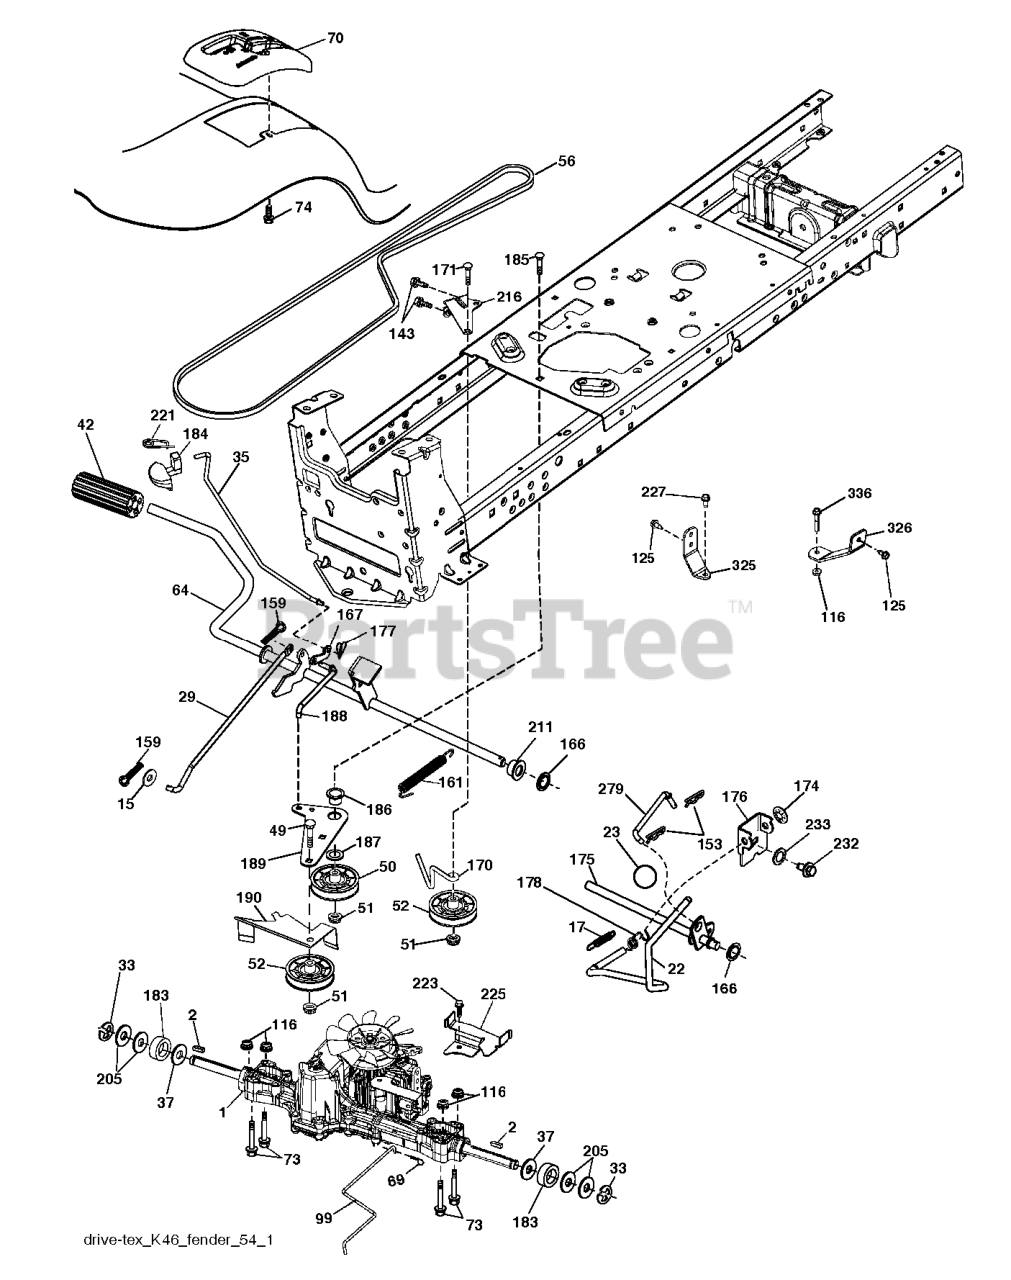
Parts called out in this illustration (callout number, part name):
2	SQUARE KEY
15	WASHER PLAIN WASHER 3/8 X 0.08
17	SPRING.BRAKE.K46.GREEN
22	ROD.SHIFT.FENDER.TLT.2006
23	KNOB.DELUXE.(PISTOL.GRIP).BLAC
29	ROD.BRAKE.K46
35	ROD ROD.PARKINGBRAKE.GT.HUSQ/P
37	WASHER.HARDENED
42	PEDAL COVER
50	IDLER.FLAT.910.OFFSET
51	NUT LOCK FLG 3/8-16 UNC
52	IDLER.V-GROOVE.910.OFFSET
64	SHAFT.ASM.PEDAL.BRAKE.
69	HAIRPIN.SOFT.ZINC.059X1.125
70	CONSOLE.SHIFT.STL.HYD.TEX.GREY
99	ARM.PIVOTING.TCRD.GEN2.5.BAGGE
125	SCREW
153	RETAINER M
161	SPRING, RETURN LT
166	NUT.PUSH.625
167	LATCH.BRAKE.SPRING
170	KEEPER.V-IDLER.CENTER.
174	NUT.PUSH.500.2006
175	SHAFT ASM SHIFT
176	ARM.CLEVIS.ROD.SHIFT
177	PIN COTTER;LOCKING;BOWTIE;1IN
178	SPRING.SHIFT.GT2006
183	SPACER AXLE
184	HANDLE.PARKING.BRAKE.H (BLK)
186	SPACER.RETAINER
188	LINK.CLUTCH.GROUND DRIVE.LONG
189	BELLCRANK.GROUND.DRIVE.TEX.
190	KEEPER.BELLCRANK.DRIVE
211	BUSHING.SHAFT.BRAKE.HAND
216	BRACKET.PULLEY.IDLER.W/TEX
221	RETAINER.SPRING.CLIP.H
225	KEEPER.BELT.TRANSAXLE.K46
279	LINK.SHIFT.T/A.K46.FEND.TX
325	BRACKET.TRQ.STP.46.20".TIRE.LH
326	BRCKT.PNT.TRQ.STP.46.20TIRE.RH
